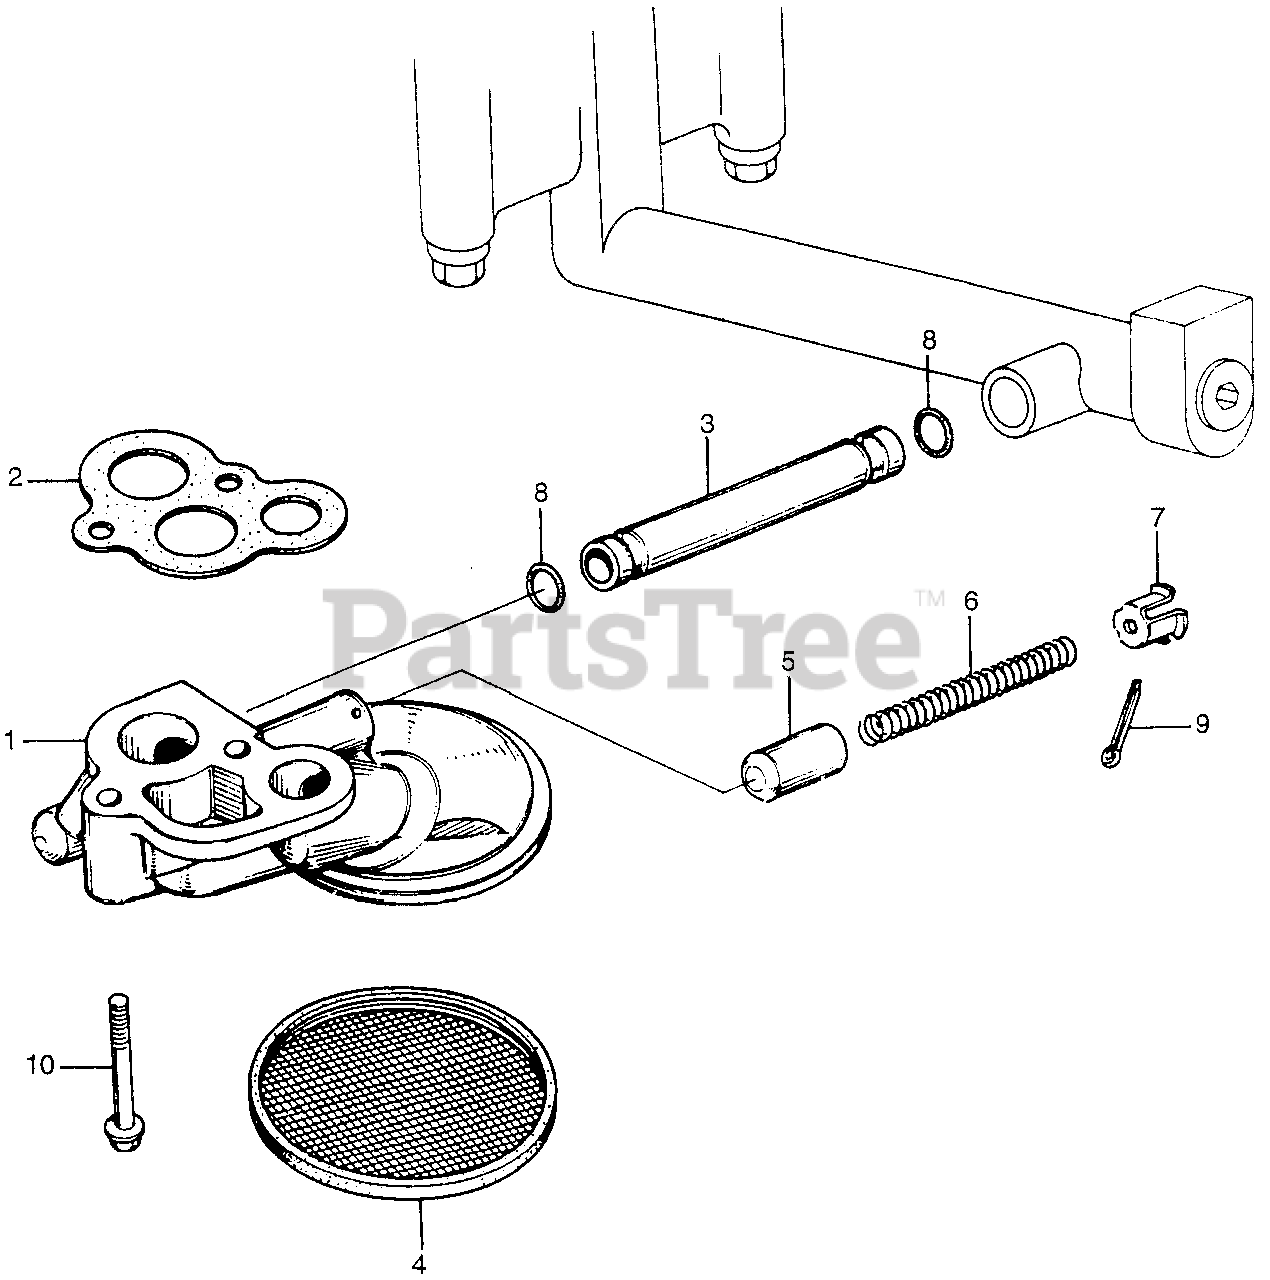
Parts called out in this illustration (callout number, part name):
1	BLOCK, OIL PASSAGE
2	GASKET, OIL PASSAGE
3	PIPE, OIL PASSAGE
4	SCREEN, OIL PUMP FILTER
5	VALVE, RELIEF
6	SPRING, RELIEF VALVE
7	SEAT, RELIEF VALVE
8	O-RING (12.5X2.2)
9	PIN, COTTER (3.0X45)
10	BOLT, FLANGE (6X32)
